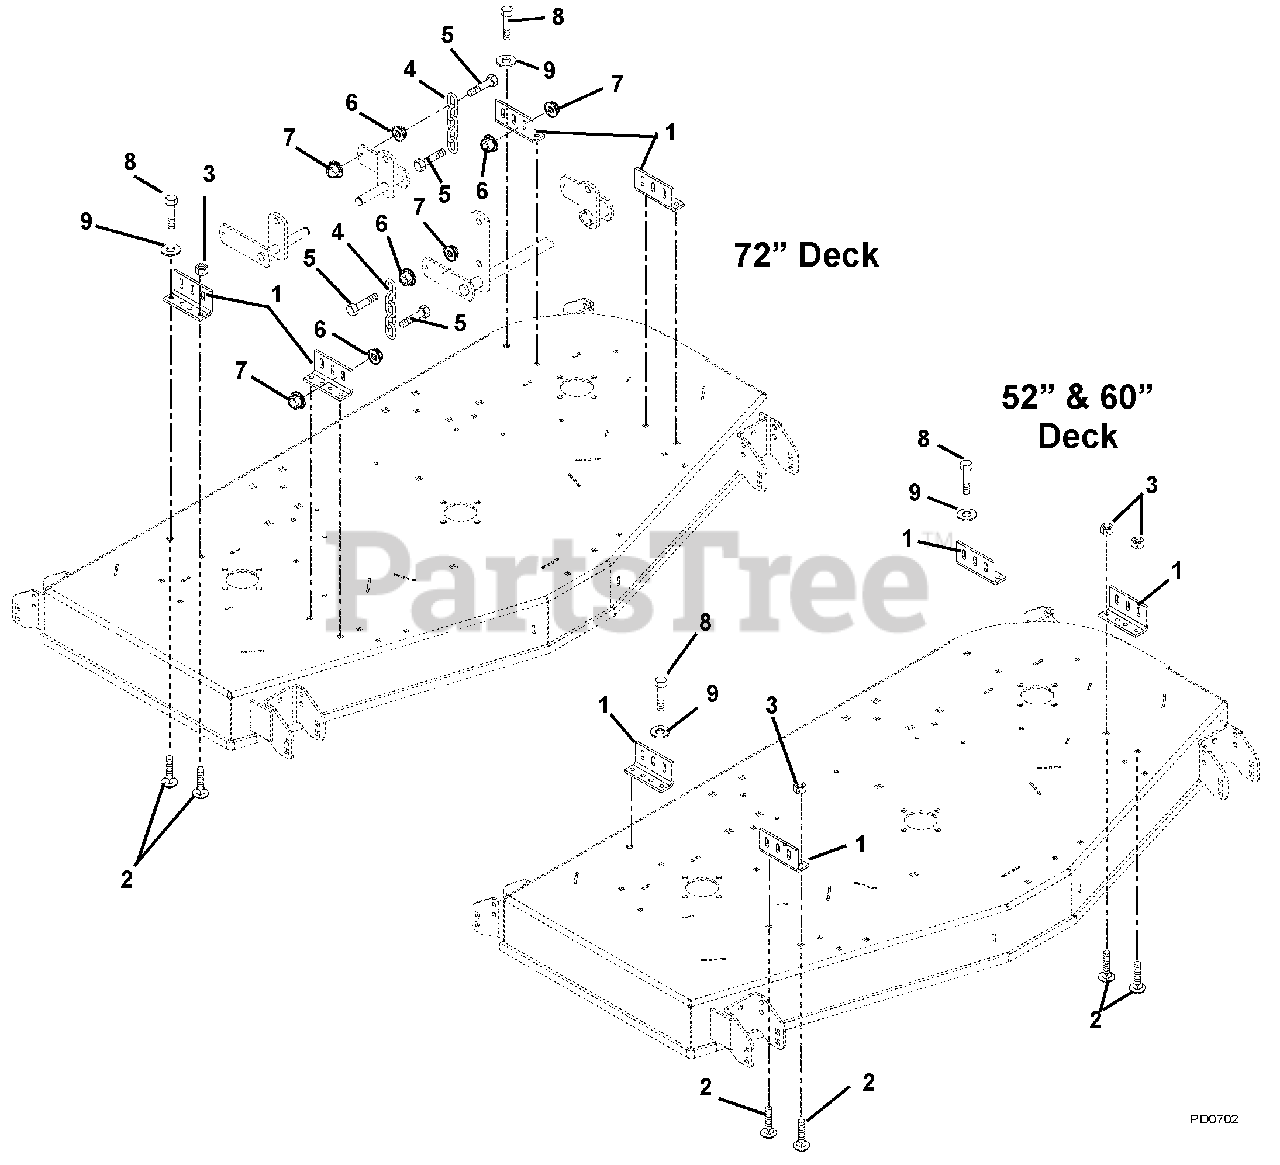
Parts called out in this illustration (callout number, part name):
1	MOWER MOUNTING BRACKET - RED
2	@BLT-RDHDSQNK .38-16X1.00 G5YZ
3	@NUT-LK-TOP-FLG .38-16 YWZC
4	CHAIN, LINK
5	BLT-HEX M12X1.75X55 GR5 YZ
6	NUT-SPNLK-FLG M12-1.75 YZ
7	NUT-LK-TOP-FLG M12-1.75 YZ
8	@BLT-HEX .38-16X1.00 GR5 YWZC
9	@WSHR-LK .38X.094 REG YWZC
